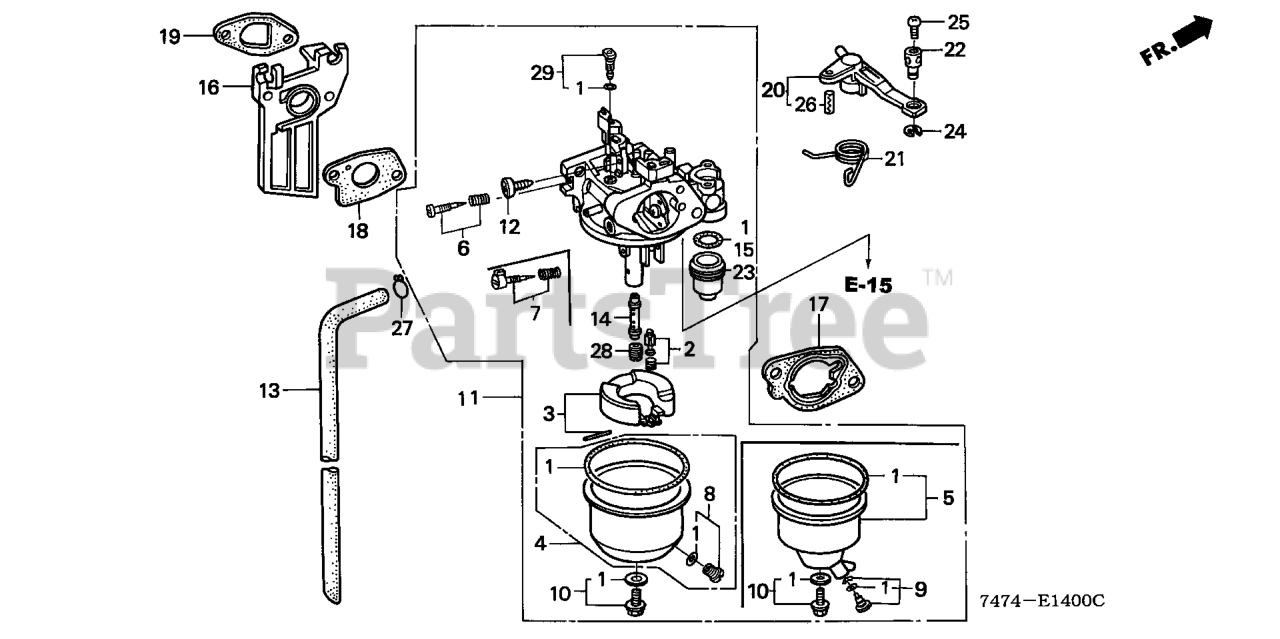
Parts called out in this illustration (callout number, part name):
1	GASKET SET
2	VALVE SET, FLOAT (CARBURETOR NO.) (SEAT NOT INCLUDED)
3	FLOAT SET
5	CHAMBER SET, FLOAT (CARBURETOR NO.)
7	SCREW SET (Honda Code 4219879). (CARBURETOR NO.)
9	SCREW SET, DRAIN (CARBURETOR NO.)
10	SCREW SET B
10	SCREW SET
11	CARBURETOR ASSY. (BE45A D)
12	SCREW, THROTTLE STOP
13	TUBE, OVERFLOW
14	NOZZLE, MAIN
15	GASKET, FUEL STRAINER CUP
16	INSULATOR, CARBURETOR
17	SPACER, CARBURETOR
18	GASKET, CARBURETOR
19	GASKET, INSULATOR
20	LEVER, CHOKE (REMOTE)
21	SPRING, RETURN
22	HOLDER, CABLE
23	CUP, FUEL STRAINER
24	CIRCLIP (5MM) Use from Engine SN 2327377.
25	SCREW, PAN (4X8)
26	PIN, SPRING (2X12)
27	CLIP, TUBE (4.5)
28	JET, MAIN (#65)
28	JET, MAIN (#68)
28	JET, MAIN (#70)
29	JET SET, PILOT (#35)
